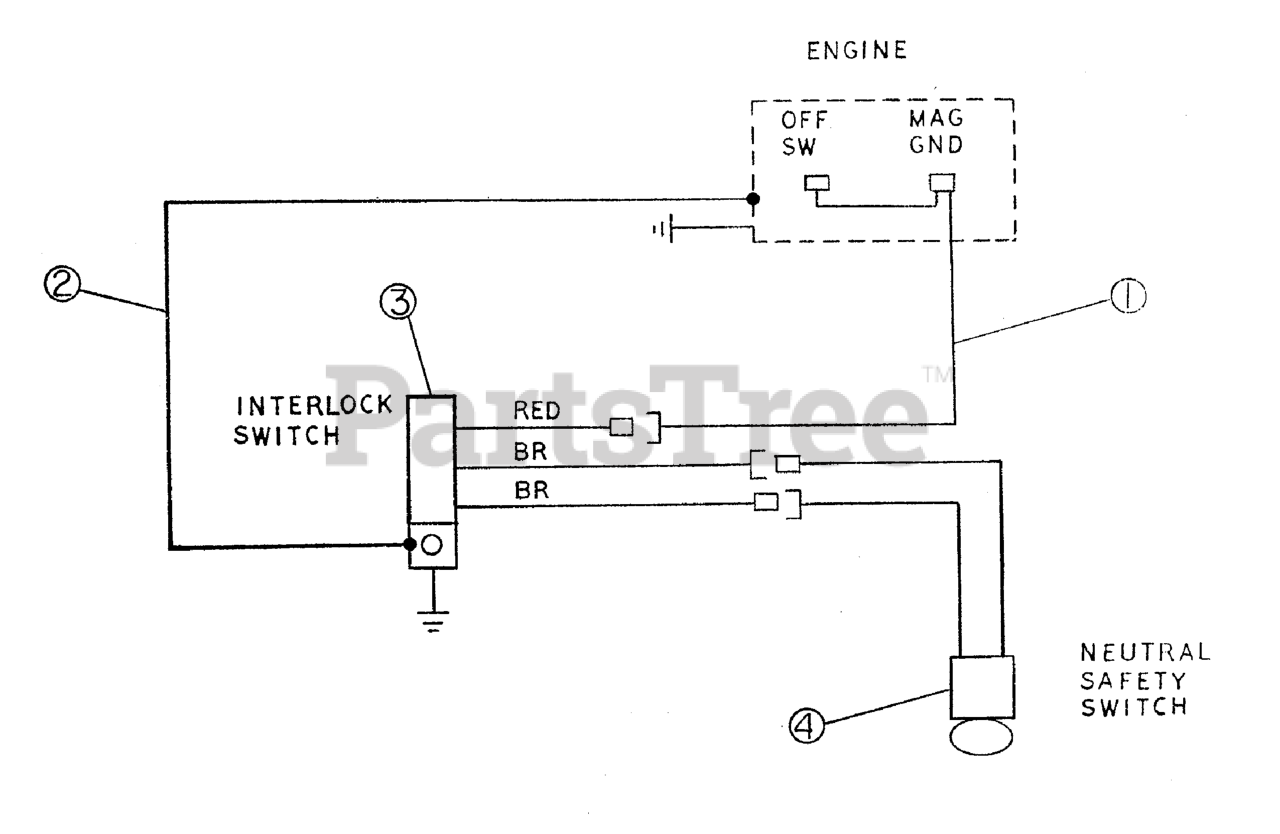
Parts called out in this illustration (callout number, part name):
1	#14 Red 9" Long Wire Assembly
2	#14 Black 5" Long Wire Assembly
3	Interlock Module
4	Neutral Safety Switch
